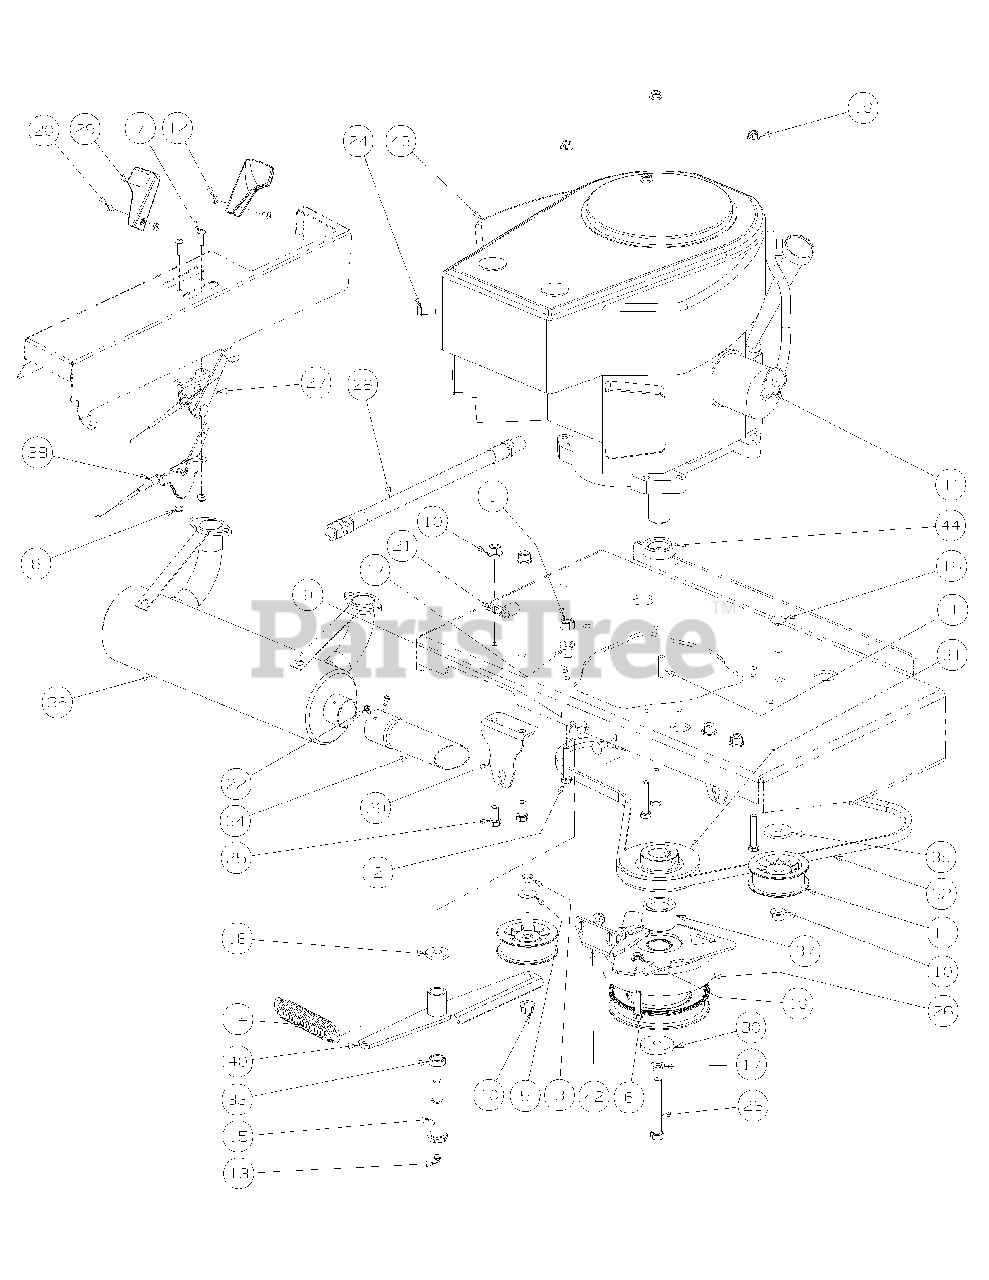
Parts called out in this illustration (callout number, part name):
1	Hex Nut, 7/16-14
2	HHCS, 5/16-18, 1-3/4
3	Capscrew, 3/8-16 x 1-3/4
4	Key, 1/4 x .875
6	Hex Cap Screw, 5/16-18 x 1.25
7	Round Hd. Machine Screw, 10-32 x 3/4
8	Lock Nut, Nylon Insert, 10-32
9	Carriage Bolt, 5/16-18 x .75
10	Flange Lock, Hex Nut, 3/8-16
11	Idler Pulley w/ Adaptor
12	Nut Washer, W/Star, 8-32
13	Grease Fitting, 1/4-28 x 3/16
14	Extension Spring, 1.0 OD x 5.00
15	Shoulder Screw, 7/16-14
16	Hex Carriage Screw, 3/8-16, 1.75
17	Lock Washer, 7/16
18	Washer, 7/16 ID x 1.75 OD x .25
19	Hexflange Lock Nut, 5/16-18
20	Machine Screw, 8-32, .375
21	Clip, Heat Shield Cable
22	Tube Clamp, 1.375
23	Hex Cap Screw, 7/16-20 x 3.0
24	Hex Cap Screw, 1.25 x 20mm
25	Hex Cap Screw, 3/8-16, .750
26	Electric Clutch
27	Choke Control Cable, 43.0
28	Oil Drain Hose
29	Control Throttle Knob
30	Flat Washer, 7/16 IDx 1.750 OD x .250T
31	Pulley, Cast, 1.125" Bore
32	V-Belt, 56.00
33	Spacer, .635 ID x .28
34	Muffler Accessory Exhaust Tube
35	Washer, 5/16-18
36	Muffler Accessory, Kawasaki
37	Spacer, 1.75 OD x 1.135 ID x 1.125
38	Throttle, Control Cable, 39.0
39	Neutral Lock Mounting Bracket
40	Engine Idler Arm Assembly Includes:
40	Bearing
41	Hose, 1/4" Dia
42	Retainer Clutch Assembly, Ogura
43	23HP Kawasaki Engine use 10W40 oil
44	Engine Spacer
